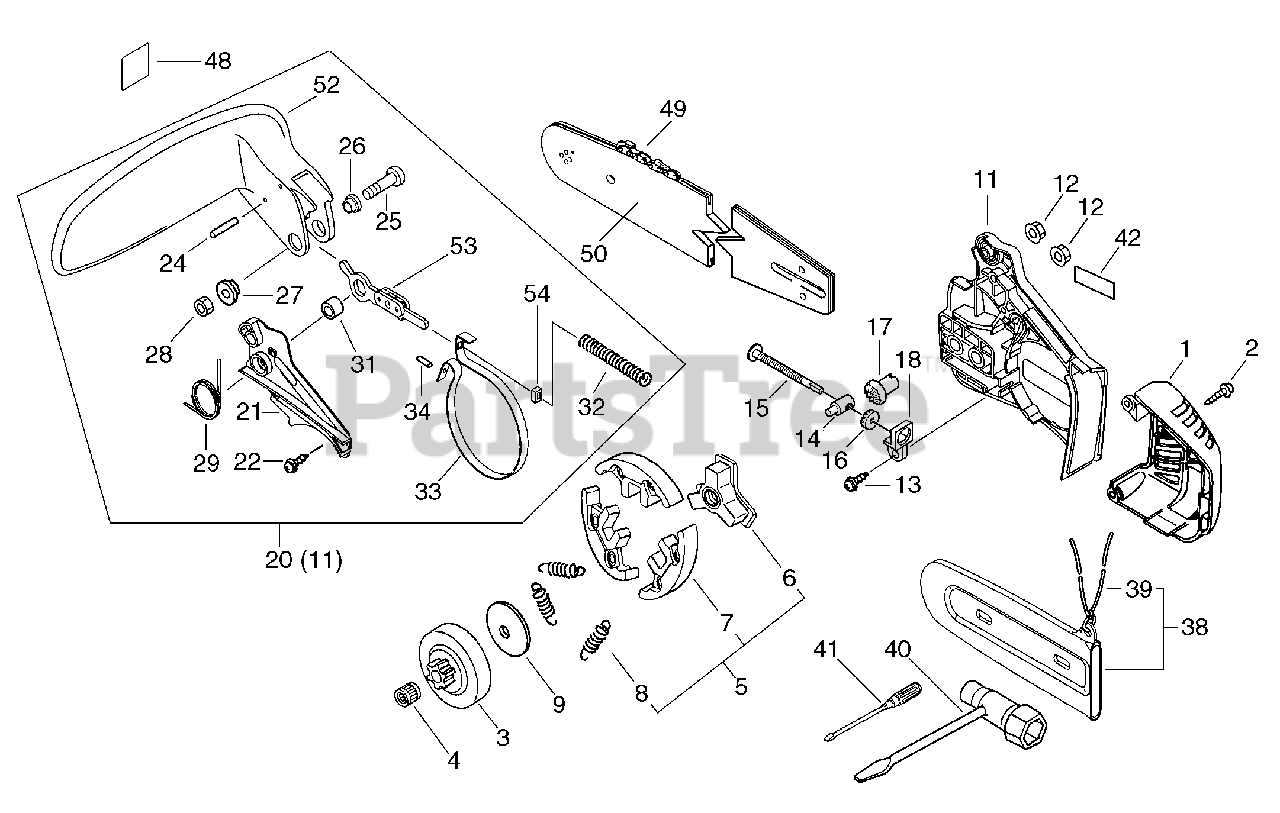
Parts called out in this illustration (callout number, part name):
1	COVER, MUFFLER
2	SCREW 4×16
3	DRUM, CLUTCH 3/8"
4	BEARING, NEEDLE
5	CLUTCH ASSY
6	HUB, CLUTCH
7	SHOE SET, CLUTCH (3PCS)
8	SPRING, CLUTCH
9	PLATE, CLUTCH
11	GUARD, SPROCKET
12	NUT, FLANGE M6
13	SCREW 4×12
14	TENSIONER, CHAIN
16	GEAR, BEVEL
17	GEAR, BEVEL
18	COLLAR 8
20	BRAKE ASSY, CHAIN
21	COVER, BRAKE
22	SCREW 4×12
24	PIN 3×26
25	SCREW 5×32
26	COLLAR 5.3×10×13×L5
27	COLLAR 5
28	NUT, LOCK M5
29	SPRING, TORSION
31	SPACER 8×12×9
32	SPRING, COMPRESSION
33	BAND, BRAKE
34	PIN, SPRING 3x-9.8
38	SCABBARD ASSY 96×350
39	ROPE 5×900
40	T-WRENCH 10×19 L= 130
41	SCREWDRIVER, PHILLIPS
42	LABEL, ECHO
48	LABEL, CAUTION
52	BRAKE, CHAIN
53	CONNECTOR, BRAKE
